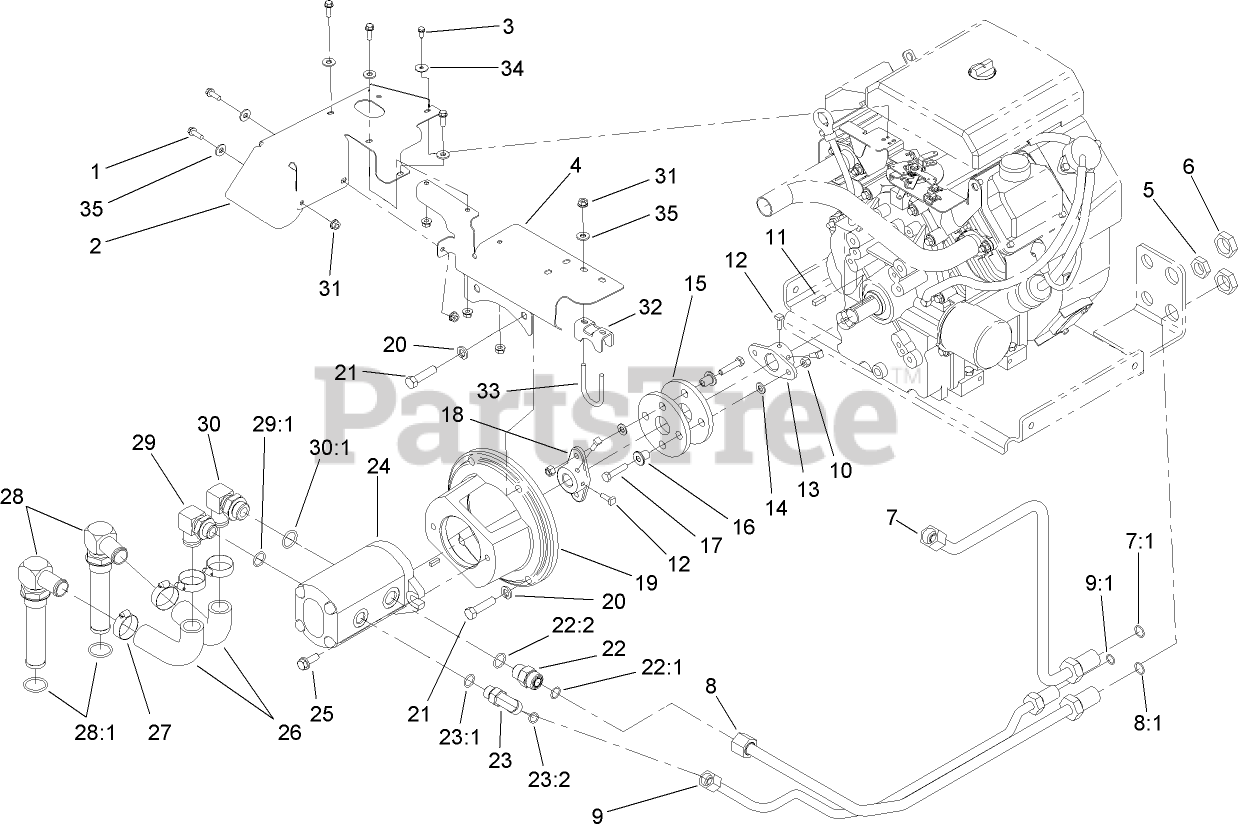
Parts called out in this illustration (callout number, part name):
1	SCREW-HWH
2	SHIELD-HEAT
3	SCREW-HWH
4	SHIELD-HEAT
5	NUT-BULKHEAD
6	NUT-LOCK, BULKHEAD
7	HYD TUBE ASM
7:1	O-RING
8	HYD TUBE ASM
8:1	O-RING
9	HYD TUBE ASM
9:1	O-RING
10	NUT-LOCK, NI
11	KEY-SQUARE
12	SCREW-SQH
13	HUB-ENGINE
14	WASHER-PLAIN
15	COUPLING-RUBBER
16	SPACER
17	SCREW-HH
18	HUB-PUMP
19	MOUNT-PUMP
20	WASHER-LOCK
21	SCREW-HH
22	FITTING-STRAIGHT
22:1	O-RING
22:2	O-RING
23	FITTING-ELBOW-90 DEG
23:1	O-RING
23:2	O-RING
24	HYD PUMP ASM
25	SCREW-HHF
26	HOSE-SUCTION, FORMED
27	CLAMP-HOSE
28	STRAINER FITTING ASM
28:1	O-RING
29	STEM-HOSE, 90 DEG
29:1	O-RING
30	FITTING-HYD, 90 DEG
30:1	O-RING
31	NUT-HHF
32	CLAMP-PIPE
33	U-BOLT
34	WASHER-FLAT
35	WASHER-FLAT
